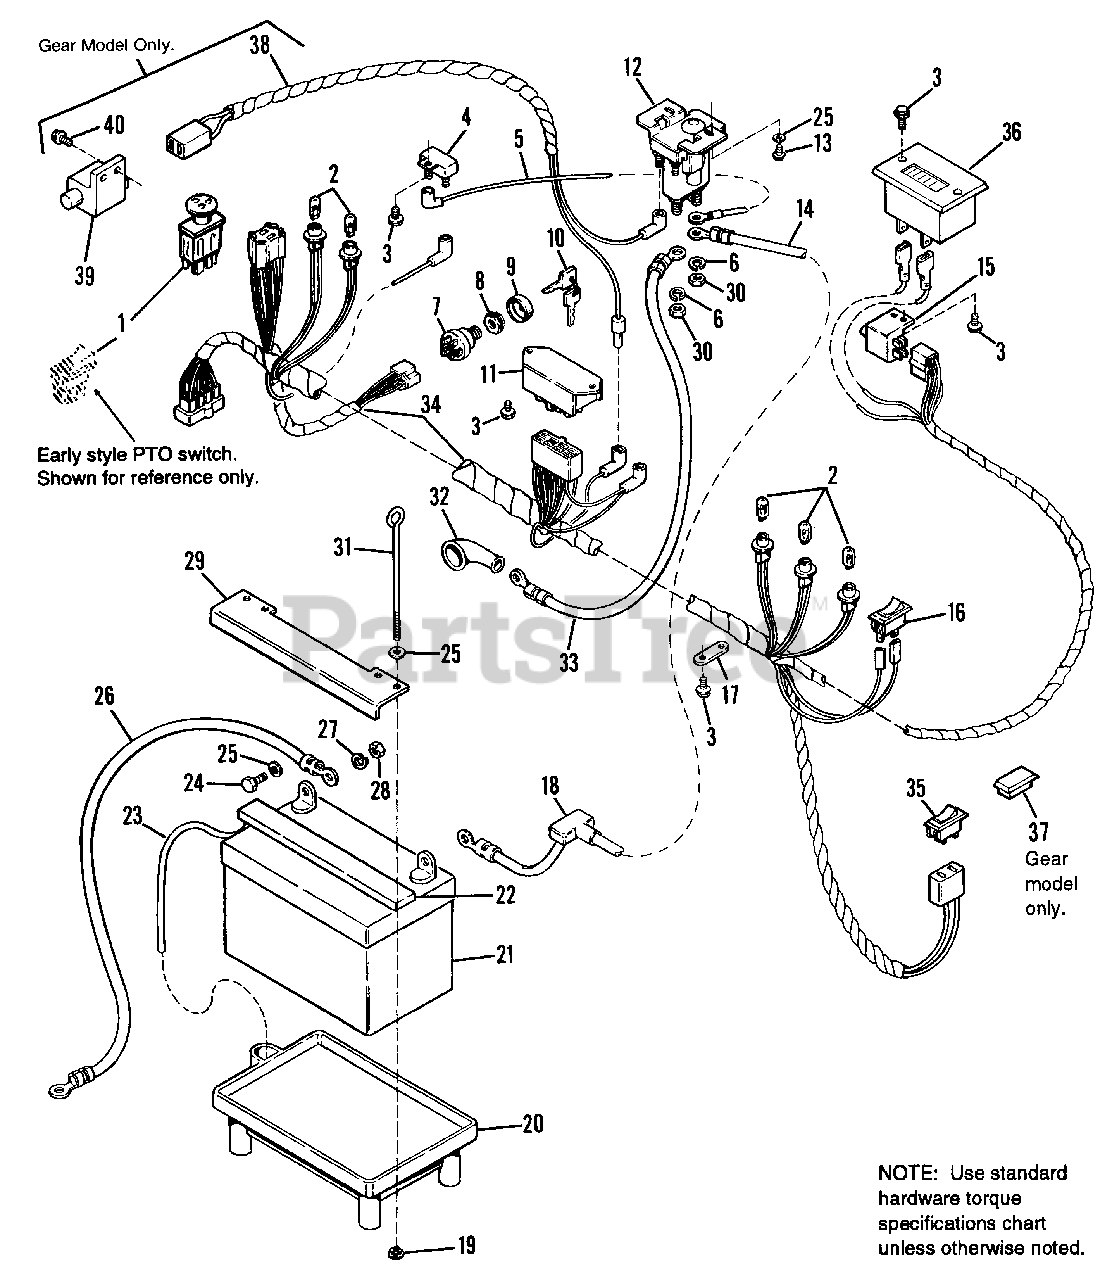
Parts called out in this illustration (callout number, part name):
1	* SWITCH, PTO, Electric Clutch
2	BULB, Indicator Light
3	SCREW, Plastite, #8-16 x 1/2
4	CIRCUIT BREAKER
6	LOCKWASHER 5/16
7	IGNITION SWITCH KIT (Incl. Ref. Nos. 8 & 10)
8	ADAPTER, Nut
9	COVER, Key Switch
12	SOLENOID
13	SCREW, Plastite, 1/4-20 x 5/8
14	CABLE, Battery-to-Solenoid
15	SWITCH, Transmission, Neutral Start
16	SWITCH, Headlight
17	STRAP, Wire Retainer
18	BOOT, Insulator
19	NUT, Plastic, 1/4-20
20	TRAY, Battery
21	BATTERY, 39 Amp (Power Max)
22	VENT, Battery
23	HOSE, Battery, Drain
24	CAPSCREW, Hex, 1/4-20 x 3/4
25	WASHER, Plain, 9/32
26	CABLE, Battery-to-Ground
27	LOCKWASHER, 1/4
28	NUT, Hex, Full, 1/4-20
29	HOLD DOWN, Battery
30	NUT, Hex, 5/16-24
31	ROD, Battery Hold Down
32	COVER, Terminal
33	CABLE, Solenoid-to-Starter
34	* HARNESS, Upper
35	SWITCH, Lift (Hydro only)
37	PLUG, Dash
38	HARNESS, Wiring
39	SWITCH
40	SCREW, Taptite 10-24 x 1/2
